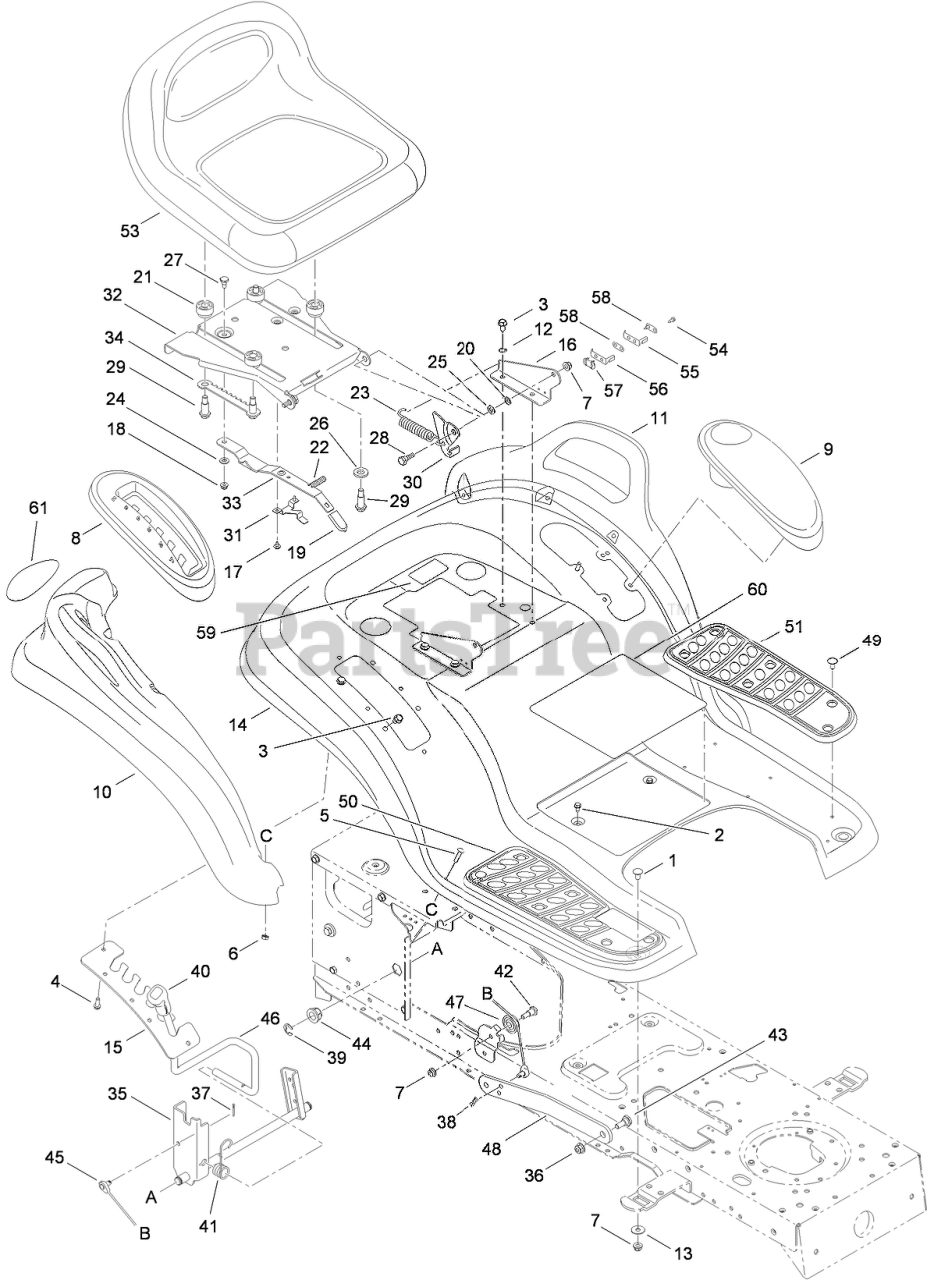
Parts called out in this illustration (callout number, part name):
1	BOLT-CARR
2	SCREW-HWHTF
3	SCREW-TAP
4	SCREW-TAP
5	SCREW-CARR
6	NUT-SEMS
7	NUT-LOCK, FLANGE
8	COVER-LEVER, LIFT
9	COVER (W/CUP HOLDER)
10	FLARE-FENDER, RH
11	FLARE-FENDER, LH
12	WASHER-LOCK, EXTERNAL
13	WASHER-FLAT
14	FENDER
15	BRACKET-ADJUSTING, LIFT
16	BRACKET-MOUNT, SEAT
17	SCREW-HH, TAP
18	NUT-LOCK, FLANGE
19	GRIP-ADJUSTER, SEAT
20	NUT-PUSH
21	SPACER-ADJUST, SEAT
22	SPRING-COMPRESSION
23	SPRING-EXTENSION
24	WASHER-BELL
25	WASHER-BELL
26	WASHER-FLAT
27	BOLT-SHOULDER
28	BOLT-SHOULDER
29	BOLT-SHOULDER
30	BRACKET-LIFT, LH
31	STOP-ADJUST, SEAT
32	BRACKET-PIVOT, SEAT
33	LEVER-ADJUST, SEAT
34	SELECTOR-ADJUST, SEAT
35	LIFT SHAFT ASM
36	NUT-LOCK, FLANGE
37	PIN-COTTER
38	PIN-COTTER
39	RING-E
40	GRIP-HANDLE
41	SPRING-TORSION
42	BOLT-SHOULDER
43	BOLT-SHOULDER
44	BEARING-FLANGE
45	CABLE-LIFT
46	HANDLE-LIFT
47	PULLEY-ROLLER
48	ARM-LIFT
49	CLIP-RATCHET, FASTENER
50	PAD-FOOT, RH
51	PAD-FOOT, LH
53	SEAT-MEDIUM BACK
54	SCREW-HWHTF
55	SWITCH-SPRING
56	SWITCH-SPRING, INNER
57	PLATE-BOSS, INSULATOR
58	PLATE-INSULATOR
59	DECAL-TORO HOTLINE
60	DECAL-SLOPE
61	REFLECTOR
